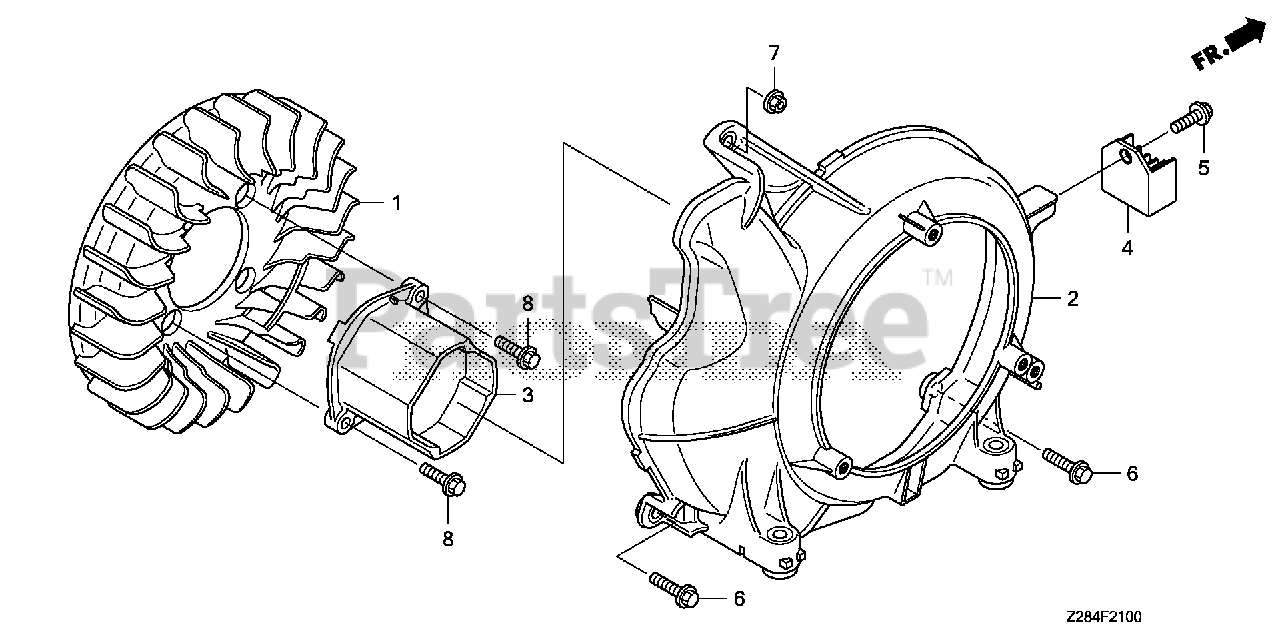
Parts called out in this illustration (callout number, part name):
1	FAN, COOLING
2	COVER, FAN
3	PULLEY, RECOIL STARTER
4	RECTIFIER ASSY.
5	BOLT, FLANGE (6X14)
6	BOLT, FLANGE (6X23)
7	NUT, FLANGE (6MM)
8	BOLT, FLANGE (6X20)
